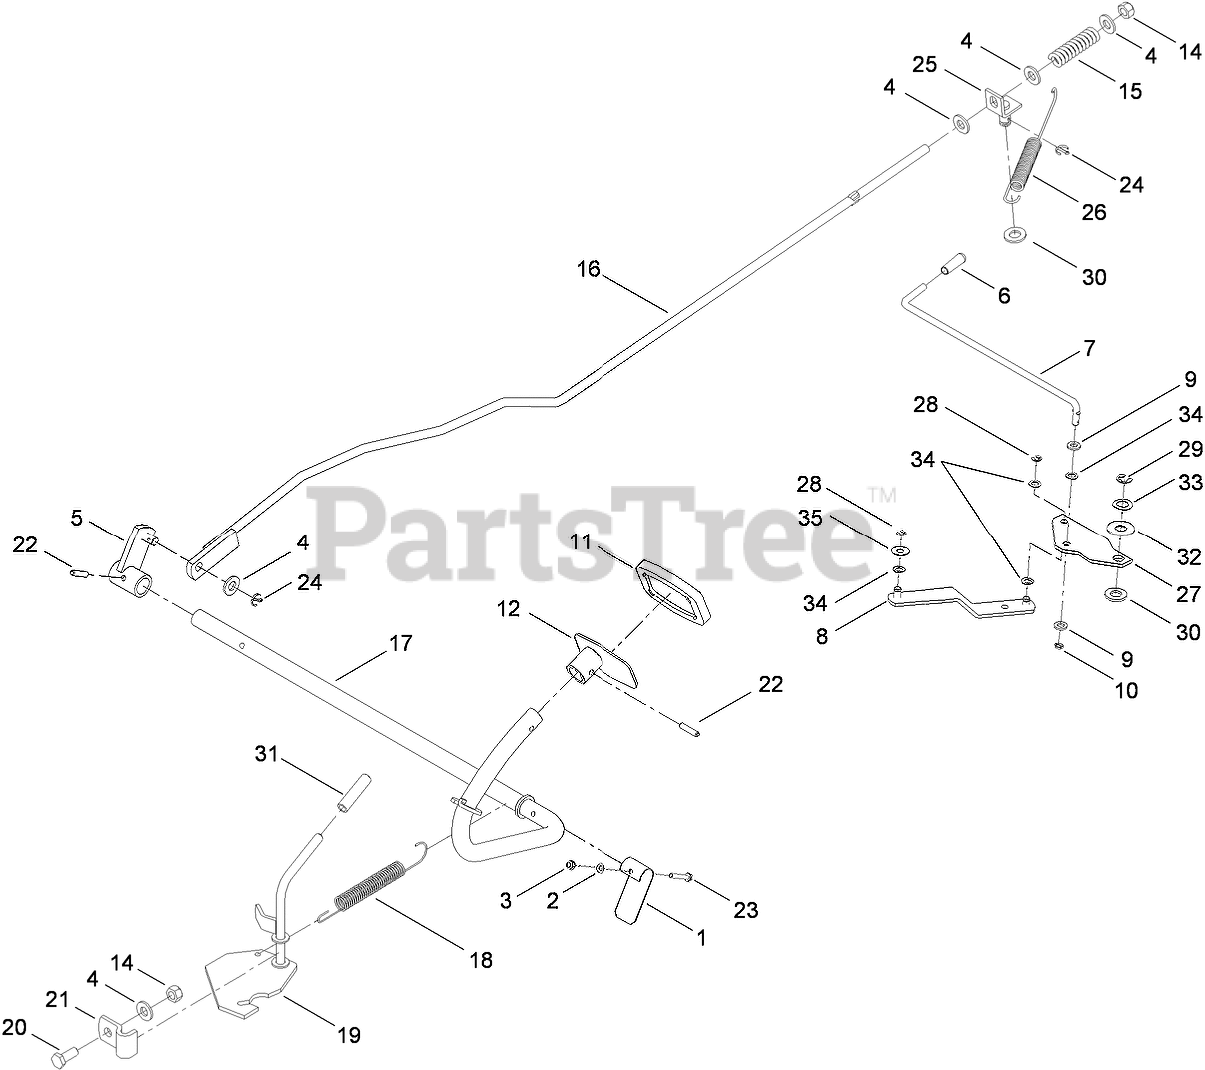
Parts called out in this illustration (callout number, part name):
1	LEVER-SPRING
2	WASHER
3	NUT-HEX
4	WASHER-PLAIN
5	BRACKET-ROD, BRAKE
6	CAP-BYPASS LEVER, HYDRO
7	ROD-LEVER, BYPASS
8	Lever-Bypass
9	WASHER
10	PIN-COTTER
11	PAD-PEDAL
12	PEDAL-BRAKE
14	NUT-LOCK, NI
15	SPRING-BRAKE
16	ROD-CONNECTING, BRAKE
17	SHAFT-BRAKE
18	SPRING-BRAKE, HAND
19	LEVER-BRAKE, HAND
20	SCREW-HH
21	CLAMP-LEVER, PARKING BRAKE
22	PIN-SPRING
23	SCREW-HEX
24	PIN-COTTER
25	BRACKET-ROD, BRAKE
26	SPRING
27	Plate-Bypass
28	STIRRUP
29	E-CLIP
30	WASHER-FLAT
32	Washer
33	Washer
34	Washer
35	Washer
